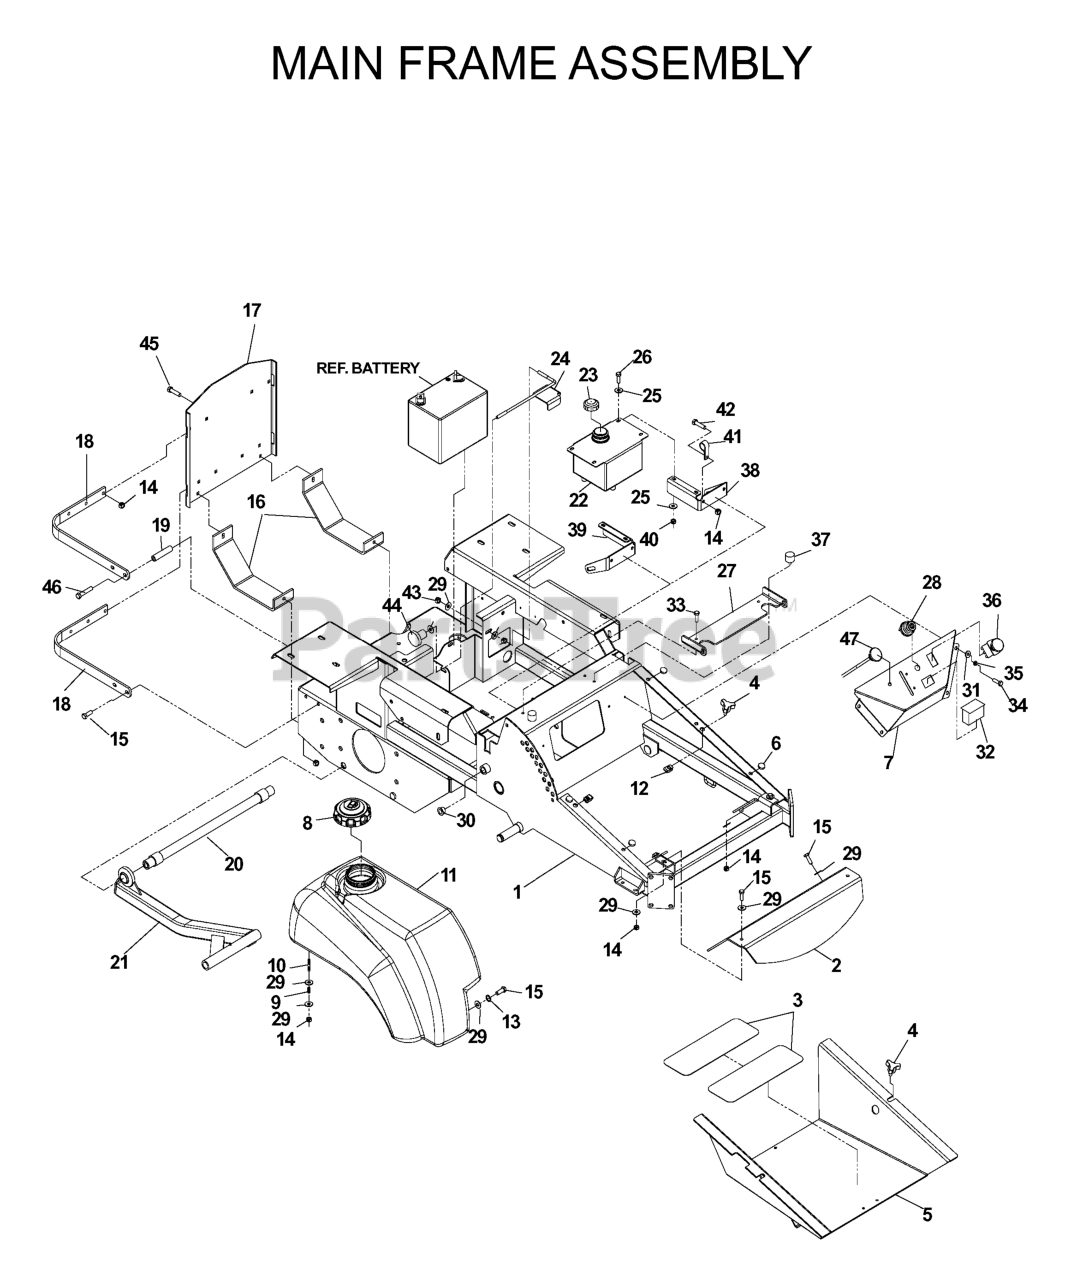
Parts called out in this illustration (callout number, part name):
1	DECK W/DECALS 61" HUS
2	FOOTREST ORANGE
3	ANTI-SKID PAD
4	KNOB W/STUD
5	FOOT PLATE
6	GROMMET, BUMPER
7	CONSOLE WLD
8	FUEL CAP ANTI-SPLASH
10	STUD, 5/16C
11	FUEL TANK RT
12	U-CLIP 5/16-18 NUT RETAINER
13	WASHER.LOCK.HVY.HLCL.SPR.5/16
14	NUT 5/16 NYLOC
15	HCS 5/16C X 1
16	SKID PLATE
17	ENGINE GUARD
18	ENGINE SHROUD BRKT
20	STRUT MOUNT WELDMENT
21	STRUT, RIGHT
23	HYDRAULIC CAP
24	BATTERY HOLD DOWN
25	WASHER 1/4 FLAT
26	HCS 1/4C X 3/4 HCS
27	SEAT BRKT W/DECAL
28	IGNITION SWITCH KIT
29	WASHER 5/16 FLAT
31	WASHER 1/4 FLAT
32	DIGITAL HOUR METER
33	HCS 1/4C X 3/4 HCS
34	SCREW 1/4 X 5/8
35	LOCKWASHER 1/4"
36	RP.SWITCH, BLADE
37	STUD/PLATE MOUNT
38	TANK MOUNT
39	TANK MOUNT
40	NUT.1/4-20.HEX.NYLOC.ZD
42	HCS 5/16C X 3/4
43	NUT 5/16C CENTERLOCK
45	RHSSNB 5/16C X 1.0
46	HCS 5/16C X 4
47	CHOKE CONTROL, COMPLETE
539102650	HOSE BARB 90 DEGREE
539102679	FUEL VALVE
539103275	THROTTLE CABLE
539104409	LEFT TANK W/CUP HOLDER
539105281	FUEL LINE 29.5"
539105527	FUEL LINE 24"
539105530	FUEL LINE 34"
539108351	STRUT, LEFT
539912222	HOSE CLAMP
